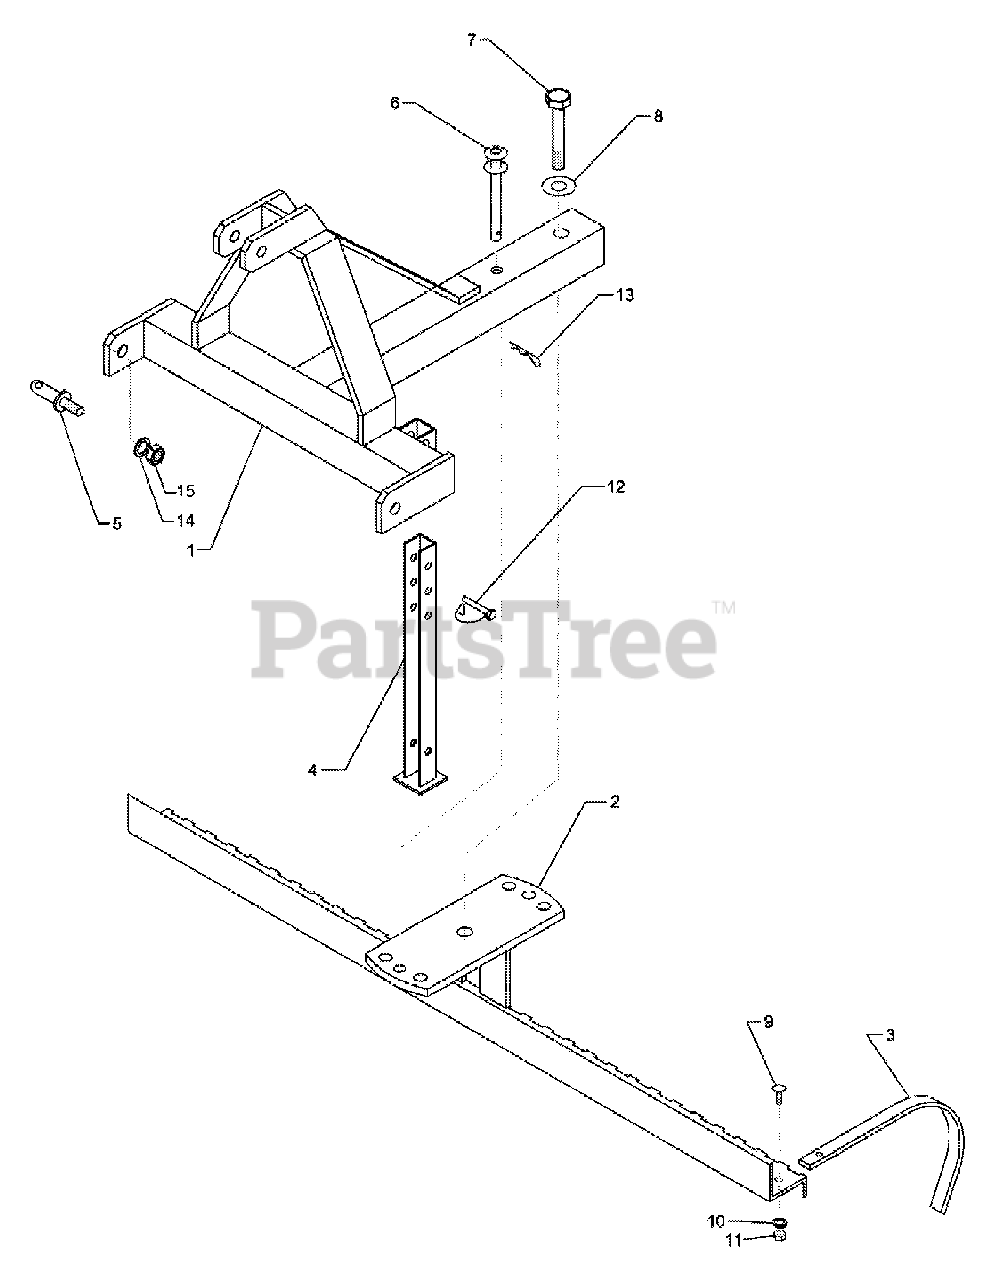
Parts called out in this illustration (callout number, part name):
2	Welded swivel (LR60)
3	Rake tine with 1 hole (LR60)
4	Foot stand
5	Hitch pin 7/8"
6	Swivel pin 3/4"x4.5" (LR60)
7	Hex bolt 3/4"x5" (LR60)
8	Flat washer 3/4" (LR60)
9	Carriage bolt 3/8"-16x1" (LR60)
10	Lock washer 3/8"
11	Hex nut 3/8"
12	Lynch pin
13	R clip Ø4
14	Lock washer 7/8"
15	Hex nut 7/8"
